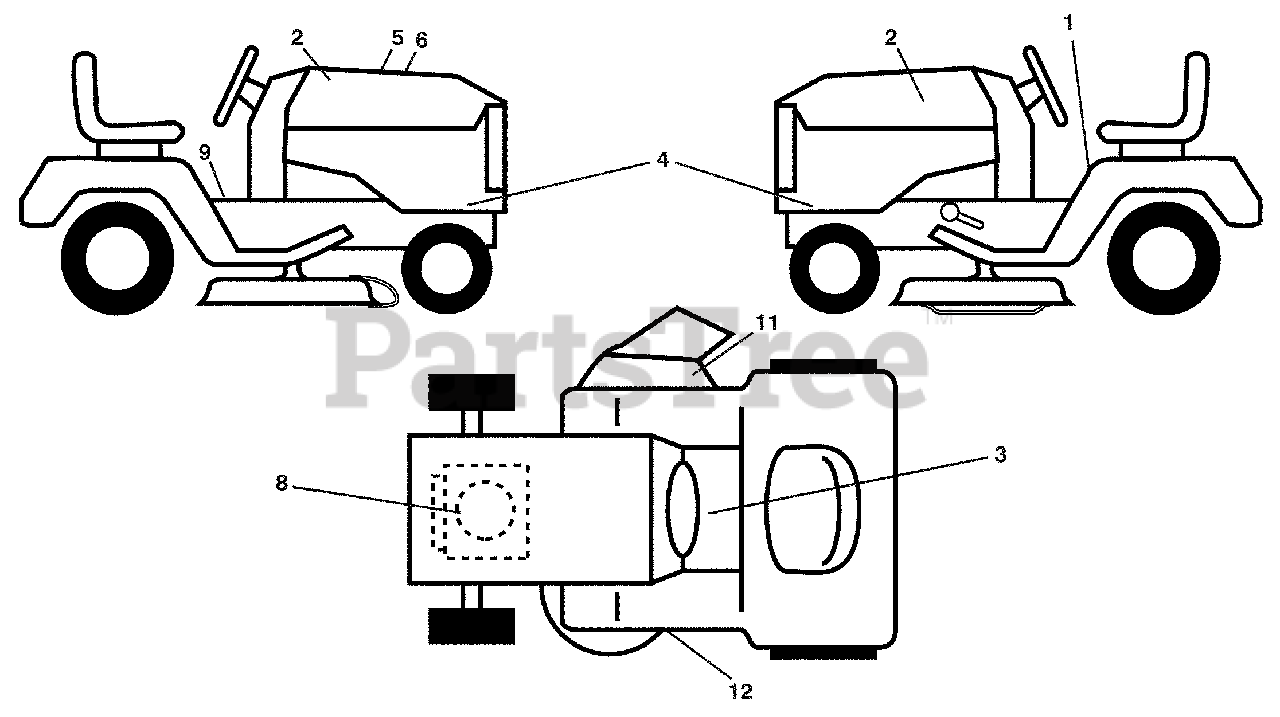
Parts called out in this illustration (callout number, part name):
1	Decal, Fender Warn./Instructions
2	Decal, Hood Logo
3	Decal, Warning Spark Arrester
4	Decal, Hood Panel
5	Decal, Customer Respons.
6	Decal, Replacement
8	Decal, Engine
9	Decal, Battery Dnge/Poi
11	Decal, Warning
12	Decal, Mower V-Belt Schematic
